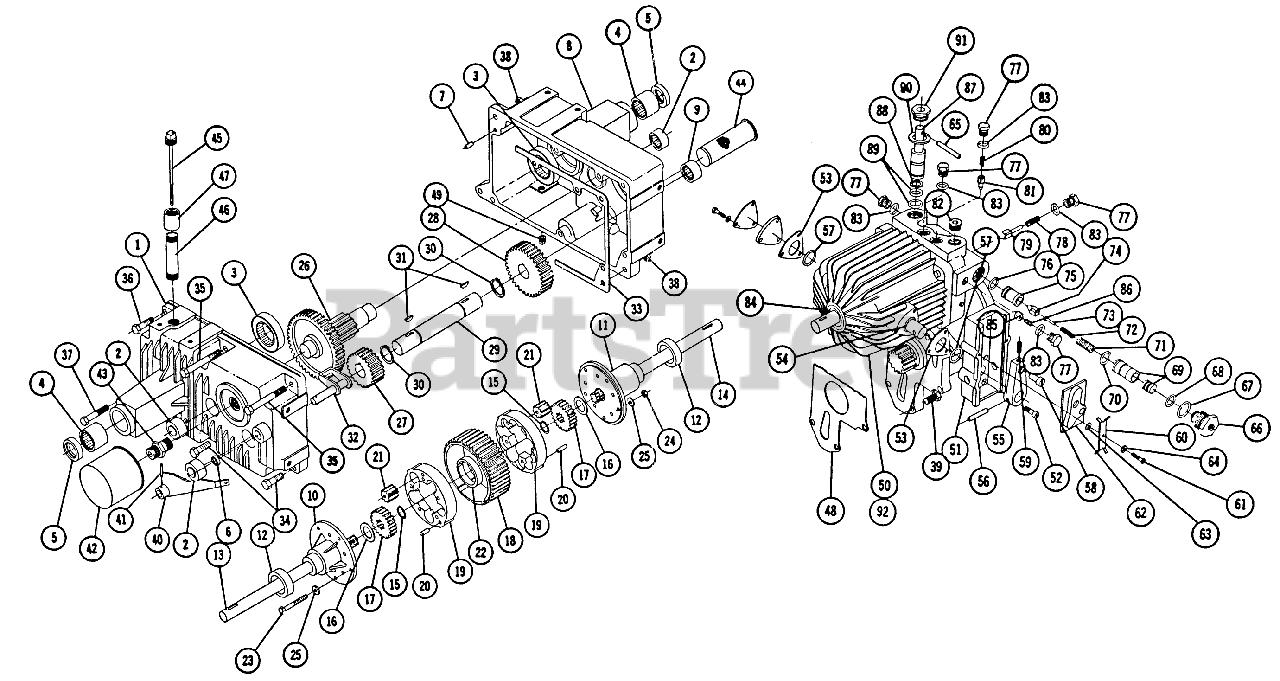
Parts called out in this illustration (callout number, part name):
1	Case RH
2	BEARING-NEEDLE
3	NEEDLE BEARING
4	Bearing-Axle
5	SEAL-OIL
6	SEAL BRAKE SHAFT
7	PIN-DOWEL
8	Case LH
9	Needle Bearing
10	End Cap-RH
11	End Cap-LH
12	RACE BEARING
13	RH AXLE
14	Axle-Rear L.H.
15	SNAP RING
16	THRUST WASHER
17	SIDE GEAR
18	Gear-Ring
19	Body
20	SPIROL ROLL PIN
21	PINION
22	Spring
23	Bolt Hex 3 1/4
24	3/8-16 E.S.
25	Washer
26	Gear
27	GEAR
28	Gear-35T
29	SHAFT GEAR
30	Snap Ring
31	Key
32	Assy.-Park Brake
33	GASKET
34	Bolt
35	H H C S
36	Bolt 3/8-16 x 2 1/4
37	Bolt Hex 3/8-16 x 1
39	Bolt, 3/8-16 x 1
40	Lever-Brake
41	Pin-Roll
42	Filter
43	FITTING
44	Strainer
45	Dipstick
46	Nipple 1/2 Pipe x 31/2
47	Coupling 1/2 Pipe
48	GASKET PUMP
49	PLUG 1/4 PIPE ALLEN
50	Hydro-Gear Unit (New)
51	SUPPORT CAM BLOCK
52	SHCS 1/4-20 X 1/2
53	Shim
54	O-Ring
55	Arm-Cam Follower
56	PIN-ROLL 1/4 X 1 1/4
58	ECC CAM FOLLOWER
59	Set Screw-1/4-20 x 1/2
60	TENSION PLATE
61	Bolt-Rd. Heed #8-32 x 1/2
62	CAM
63	Washer
64	Lockwasher
65	SPIROL PIN
66	Ass-y Dampening Valve & Ring
67	O RING
68	O RING
69	Ass-y Piston & Sleeve (Matched)
70	O RING
71	Spring Relief Valve
72	SPRING
73	SUNDSTRAND 3100047
74	Cone-Relief Valve
75	SLEEVE RELIEF VALVE
76	O RING
77	Plug
78	SPRING-SUNDSTRAND
79	Valve
80	Spring Charge Pump Valve
81	Cone
83	O RING
84	SEAL
85	Cone
86	Spring
87	WIRE ASSY
88	RING BACK UP
89	O-Ring
90	Washer
91	PLUG
92	Hydro-Gear Unit (Rebuilt)
